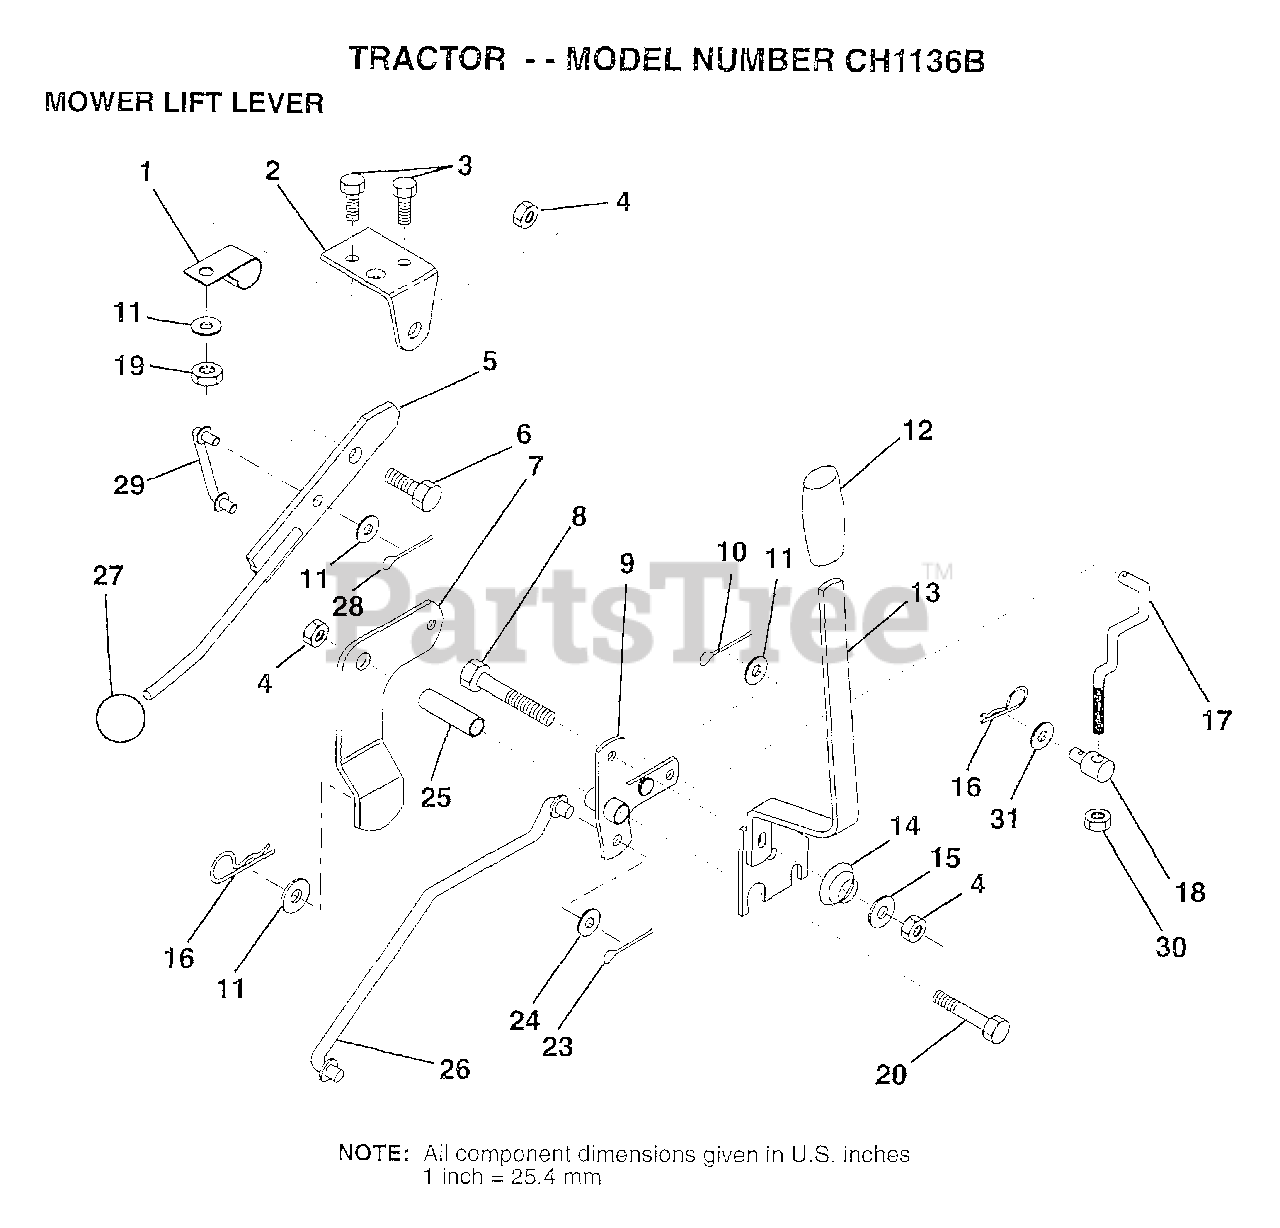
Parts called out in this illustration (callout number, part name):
1	"CLIP,INSULATOR"
2	BRKT CLUTCH
3	BOLT HXHD FIN
5	LEVER.ASM.CLUTCH
6	"BOLT, SHOULDER LT"
7	MWR CLUTCH ARM AS
8	BOLT
9	"BELLCRANK,LIFT"
10	COTTER PIN
11	WASHER
13	HANDLE.ASM.LIFT
14	SPRING COMPRESSIO
15	WASHER T
16	SPRING.RETAINER
17	"LINK,LIFT FRT"
18	TRUNION ADJ
20	BOLT
23	PIN COTTER 1/8
25	TUBE SPACER
26	ROD LIFT MOWER
27	KNOB T(3/8 HOLE)
29	CLUTCH LINK
30	NUT
31	WASHER
